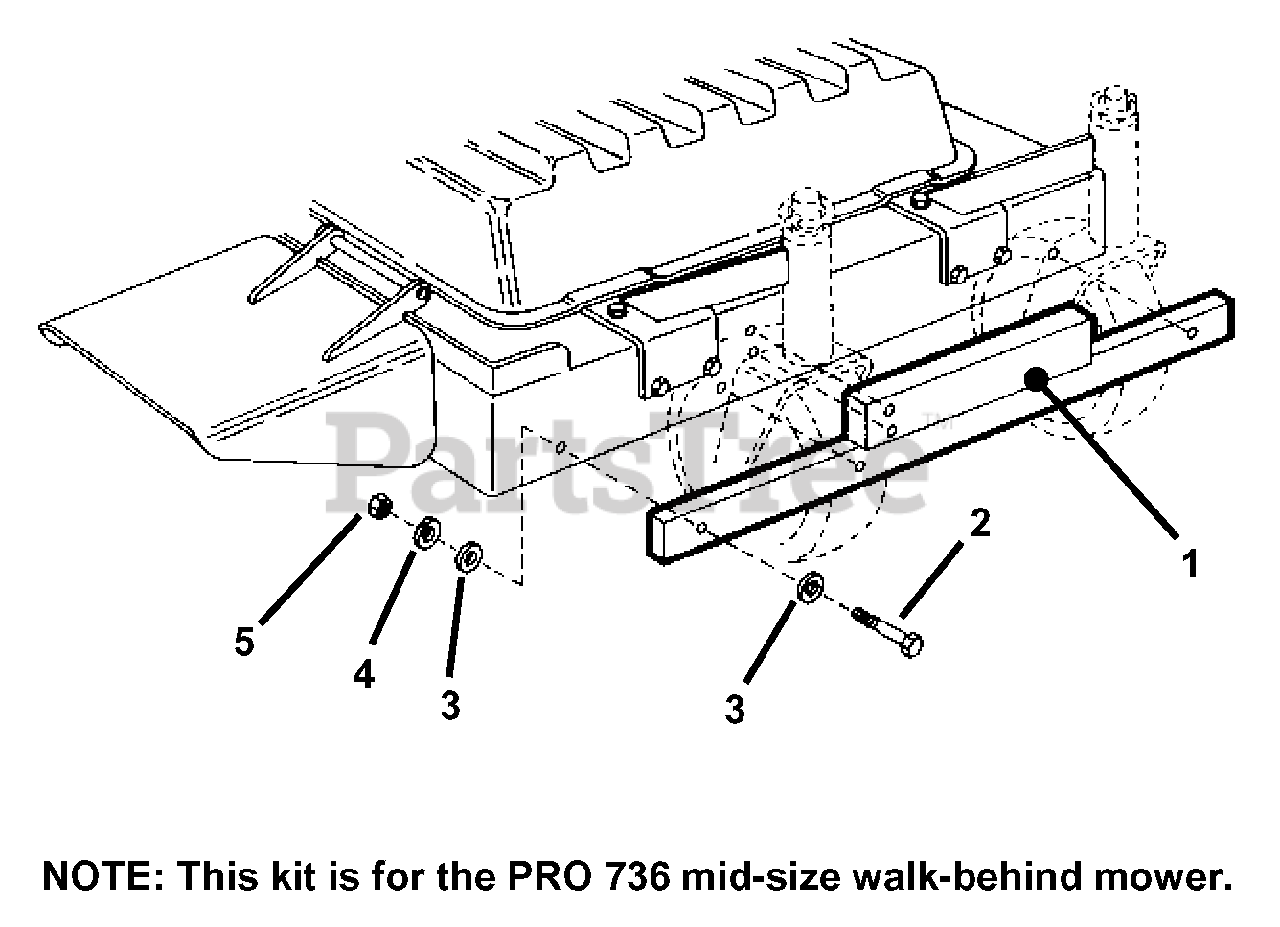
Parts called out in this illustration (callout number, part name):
1	STRUCTURE, Front Ballast
2	BOLT, 3/8-16 x 2-1/4" Hex Head, Grade 5
3	WASHER, 3/8" Flat
4	WASHER, 3/8" Split Lock
5	NUT, 3/8-16 Hex Nyloc
